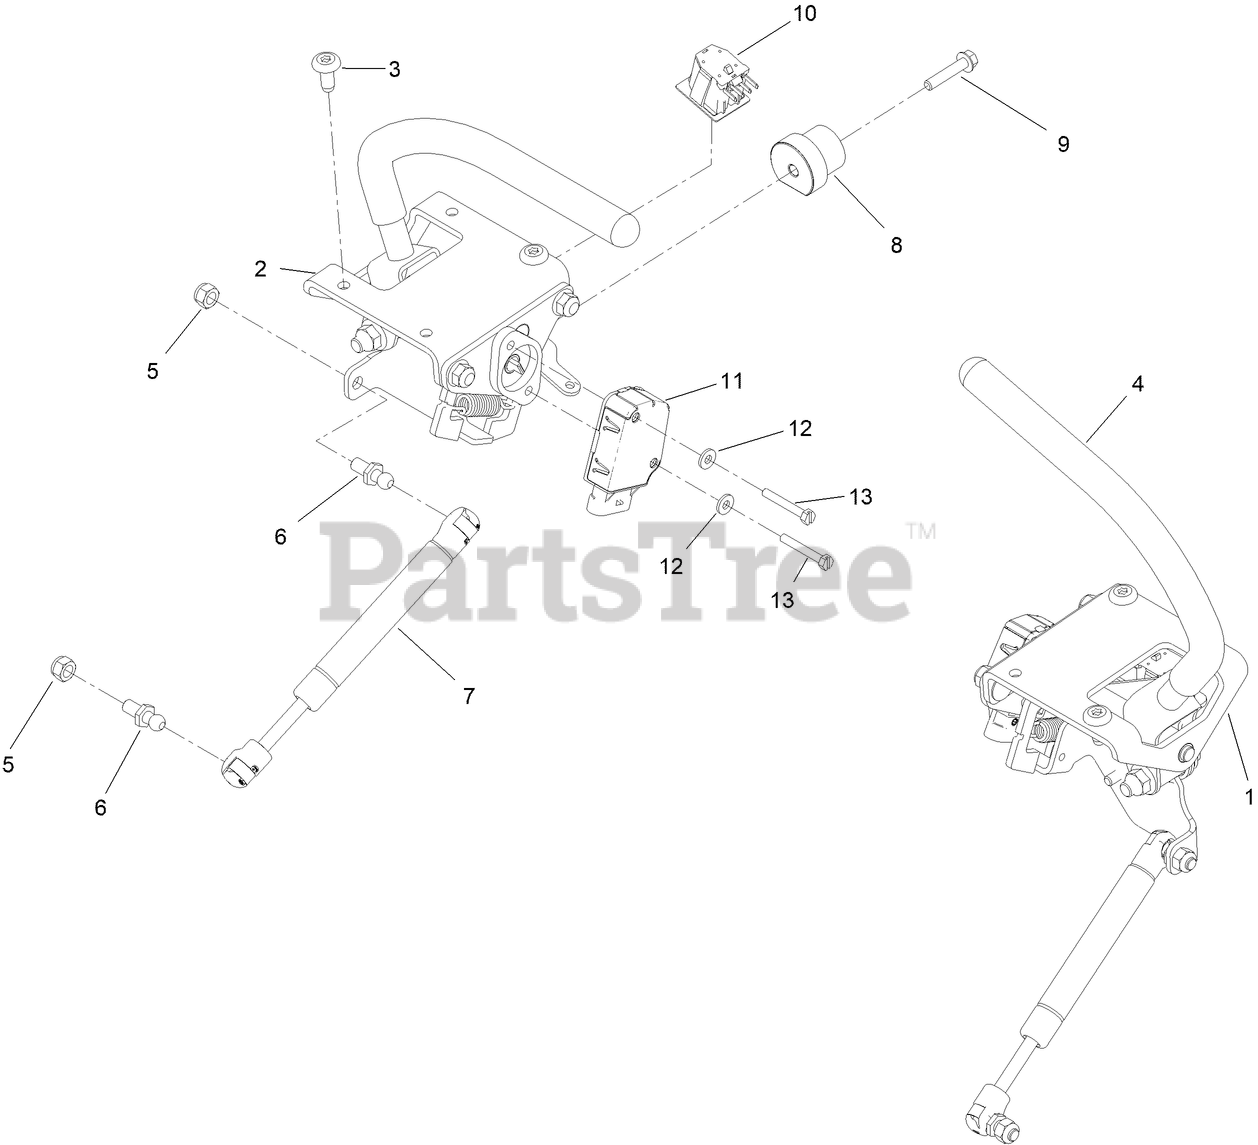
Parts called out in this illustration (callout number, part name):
1	CONTROL HANDLE ASM, LH
2	CONTROL HANDLE ASM, RH
5	NUT-HF
6	STUD-BALL
7	DAMPER
9	SCREW-HWH
10	SWITCH-PLUNGER, ON-(ON)
11	SENSOR-POSITION
12	WASHER-FLAT
13	SCREW-SHH
